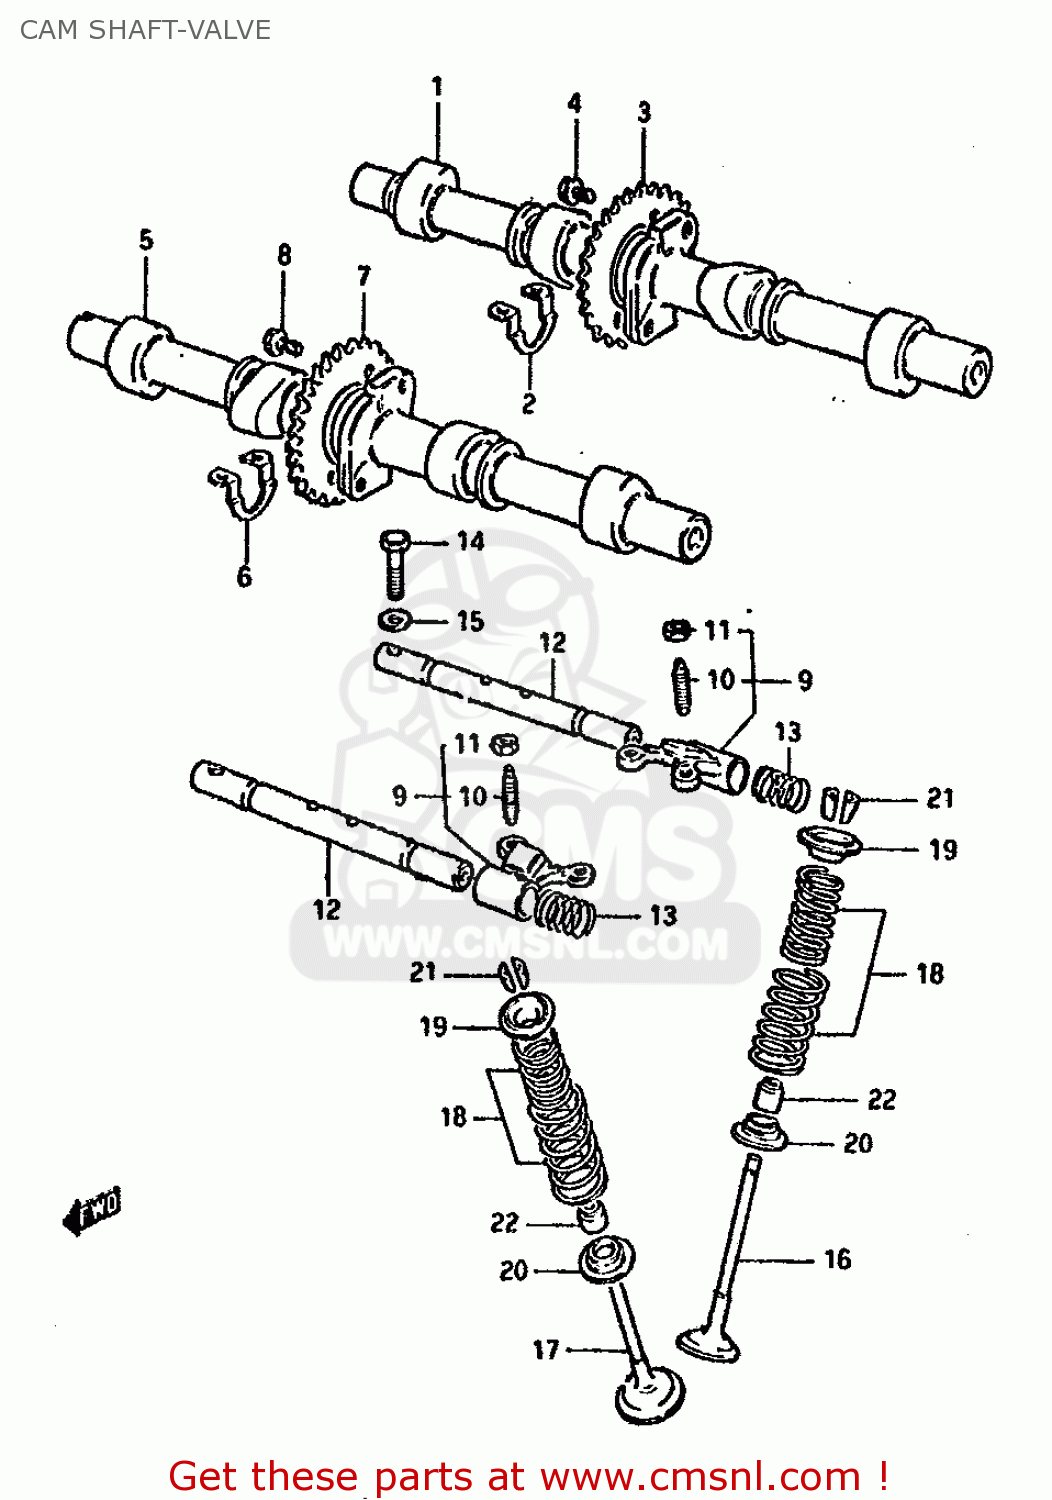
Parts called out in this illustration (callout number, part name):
1	CAMSHAFT SET,INTAKE
2	SHIM,CAMSHAFT
3	SPROCKET,INTAKE CAMSHAFT
4	BOLT(7X11)
5	CAMSHAFT SET,EXHAUST
6	SHIM,CAMSHAFT
7	SPROCKET,EXHAUST CAMSHAFT
8	BOLT(7X11)
9	ARM,VALVE ROCKER
10	SCREW,TAPPET ADJUSTING
11	NUT,ADJUSTING
12	SHAFT,VALVE ROCKER
13	SPRING
14	BOLT
15	WASHER
16	VALVE,INTAKE
17	VALVE,EXHAUST
18	SPRING SET,VALVE
19	RETAINER,VALVE SPRING
20	SEAT,VALVE SPRING
21	COTTER VALVE
22	OIL SEAL
